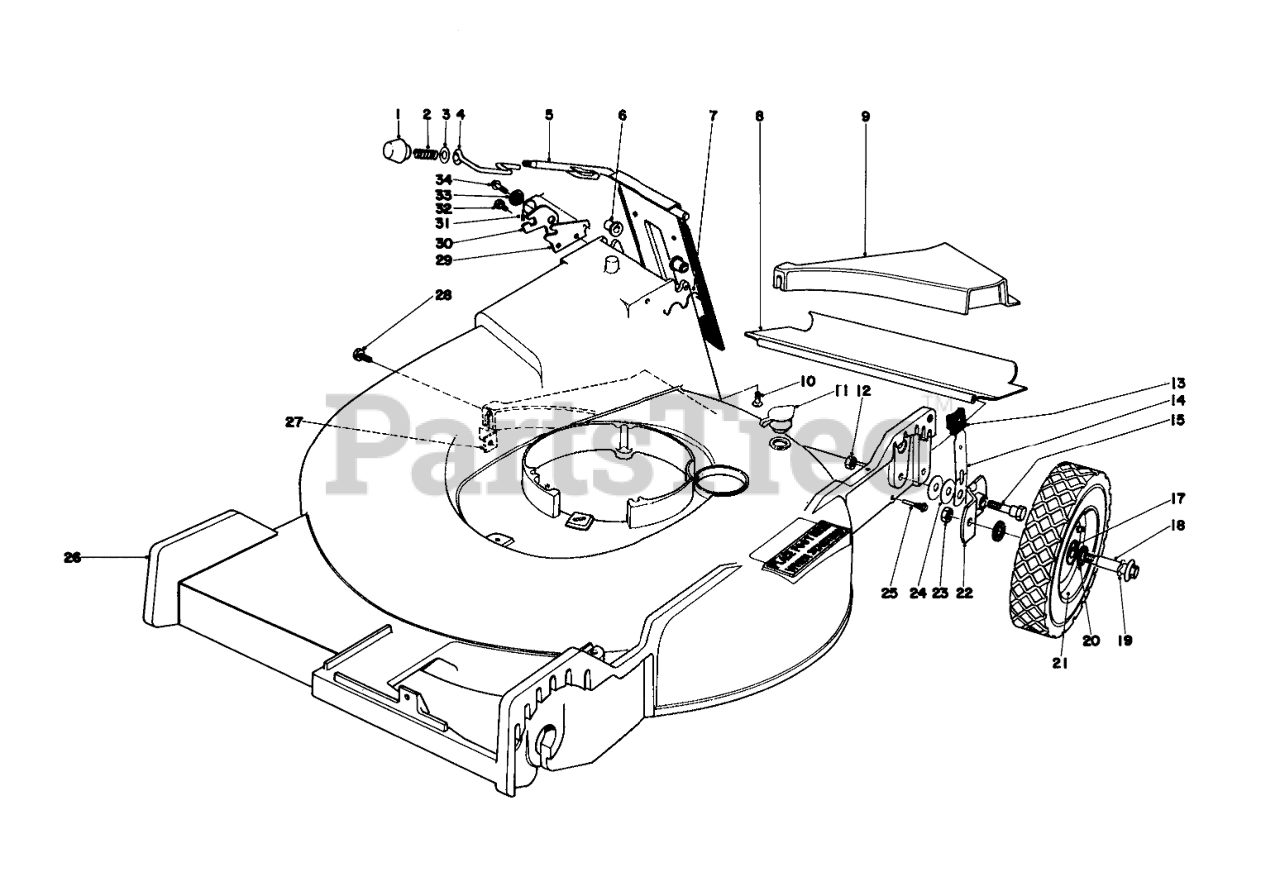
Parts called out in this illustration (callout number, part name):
2	COMPRESSION SPRING
3	WASHER
4	DOOR LATCH
5	Door Handle
6	BUSHING-NYLON
7	Door Retainer
8	REAR SAFETY SHIELD
9	REAR INSERT
10	SCREW-HH
11	WASHOUT PLUG
12	Nut
13	KNOB-ARM
14	SPRING ARM ASM
15	PIVOT SCREW
17	BEARING-BALL
19	SPRING WASHER
20	FELT WASHER
21	Wheel & Tire Assembly (Incl. Ref #17)
22	PIVOT ARM ASM A
23	Nut
24	WASHER-PIVOT
25	SAFTEY SHIELD SCREW
26	Housing
27	SPECIAL NUT
28	SCREW THD 1/4 20 5/8
29	DOOR LATCH PLATE
30	Latch Safety
31	TORSION SPRING
32	SCREW-HWH
33	Latch Spacer
34	Screw
